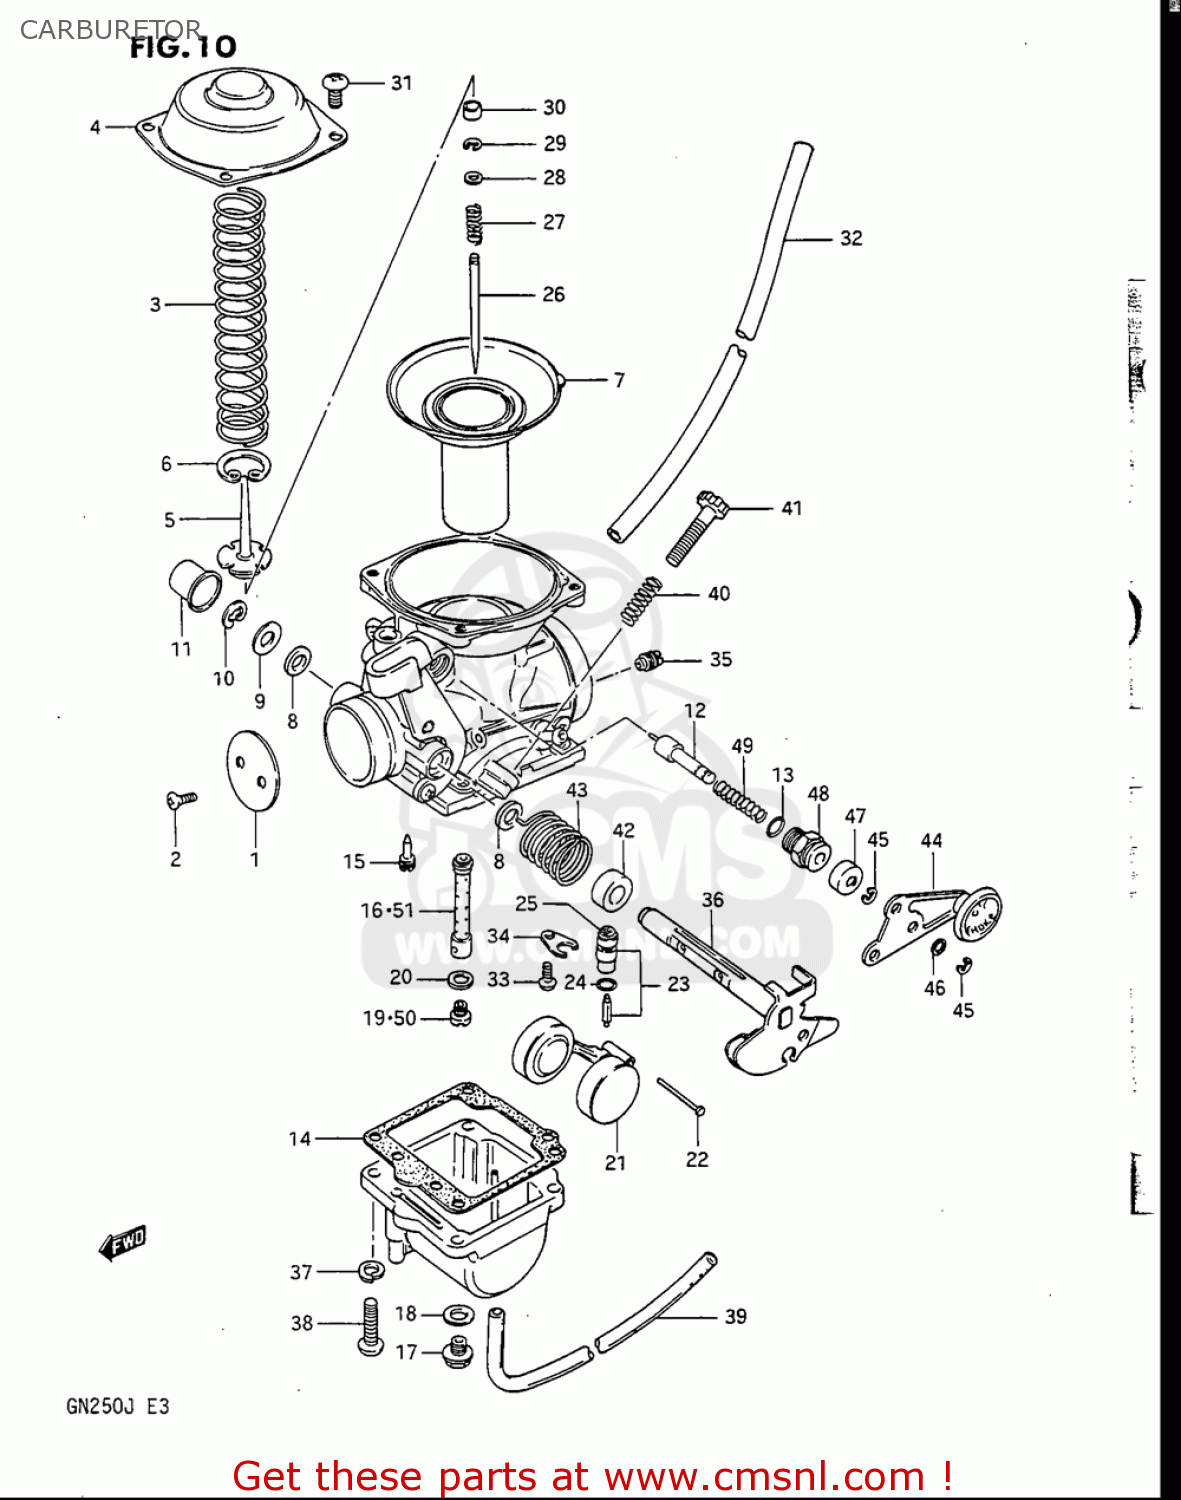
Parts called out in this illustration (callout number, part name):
2	SCREW
3	SPRING
4	COVER
5	HOLDER,GUIDE
6	E RING
7	DIAPHRAGM ASSY
8	SEAL
9	GASKET,THROTTLE SHAFT (NAS)
10	E RING
11	CAP
12	PLUNGER ASSY
13	O RING
14	GASKET,FLOAT CAHMBER (NAS)
15	JET,PILOT(42.5)
17	PLUG,DRAIN
18	GASKET (NAS)
19	JET,MAIN(130)
20	WASHER
21	FLOAT
22	PIN,FLOAT
23	VALVE ASSY,NEEDLE
24	O RING,NEEDLE VALVE SEAT
25	FILTER
27	SPRING
28	WASHER
29	CLIP
30	RING
31	SCREW
32	HOSE(5X8.2X600)
33	SCREW 4X6
34	PLATE
35	JET,AIR(150)
37	WASHER,LOCK
38	SCREW
39	HOSE(3.5X6.5X600)
40	SPRING,THROTTLE SCREW
41	ADJUSTER
42	RING
45	E RING
46	WASHER
47	CAP,STARTER VALVE
48	GUIDE SCREW,PLUNGER
49	SPRING
50	JET,MAIN(127.5)
51	JET,NEEDLE
